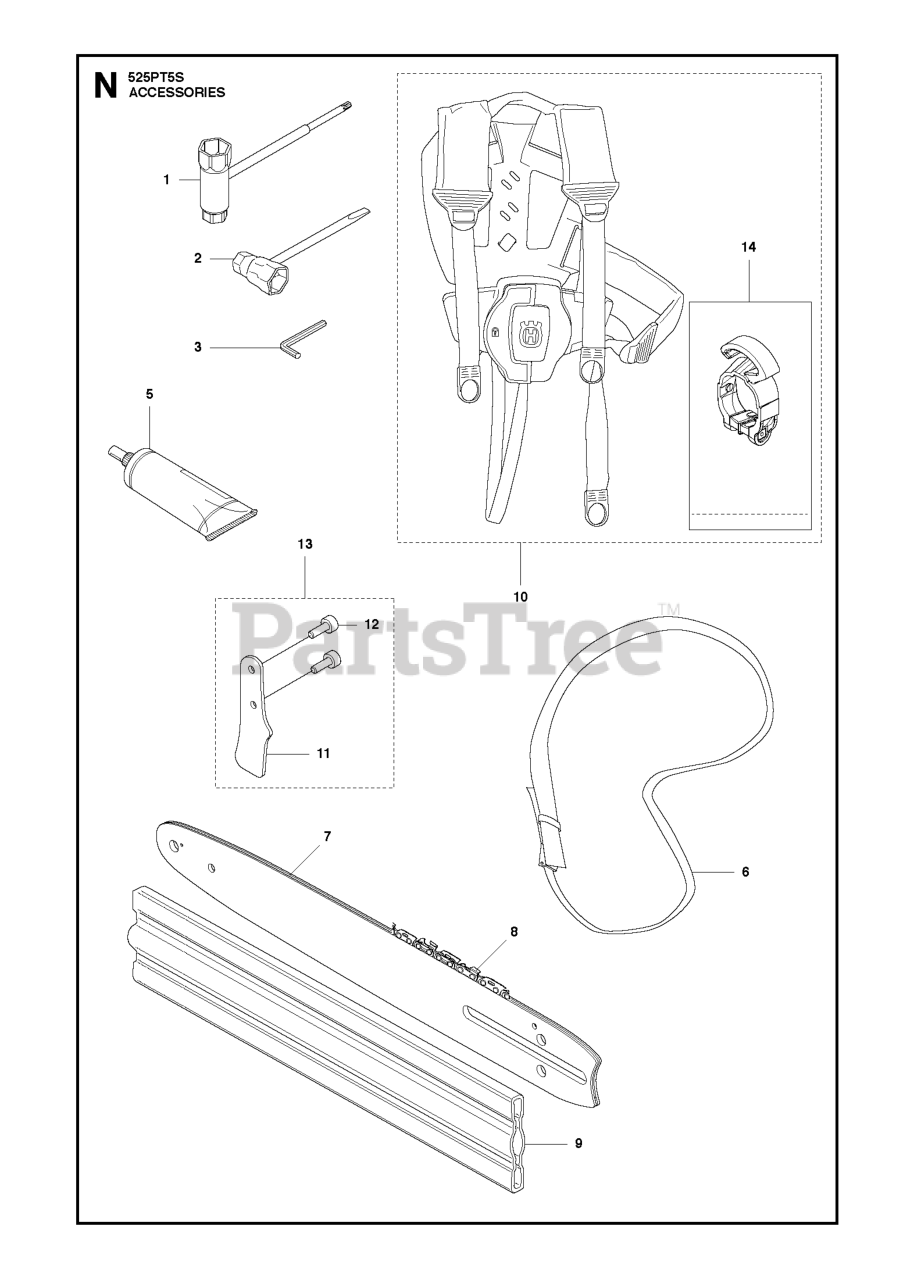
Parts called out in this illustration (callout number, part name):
1	COMBINATION WRENCH TORX
2	COMBI TOOL
5	GREASE
6	HARNESS WITHOUT HOOK
7	12" DOUBLE GUARD BAR
7	BAR 1/4" A318 10" 58DL
7	12" BAR, 1/4, .050 A318
8	SAW CHAIN H00 58DL MICRO CHISE
8	RP12" CHN H35-44 3/8 MINI,.050
8	SAW CHAIN H00 64DL MICRO CHISE
10	HARNESS BALANCE FLEX
11	SHEET HOOK
12	SCREW ITXSCM
13	HOOK
14	ACCESSORY BAG HARNESS HOOK 525
